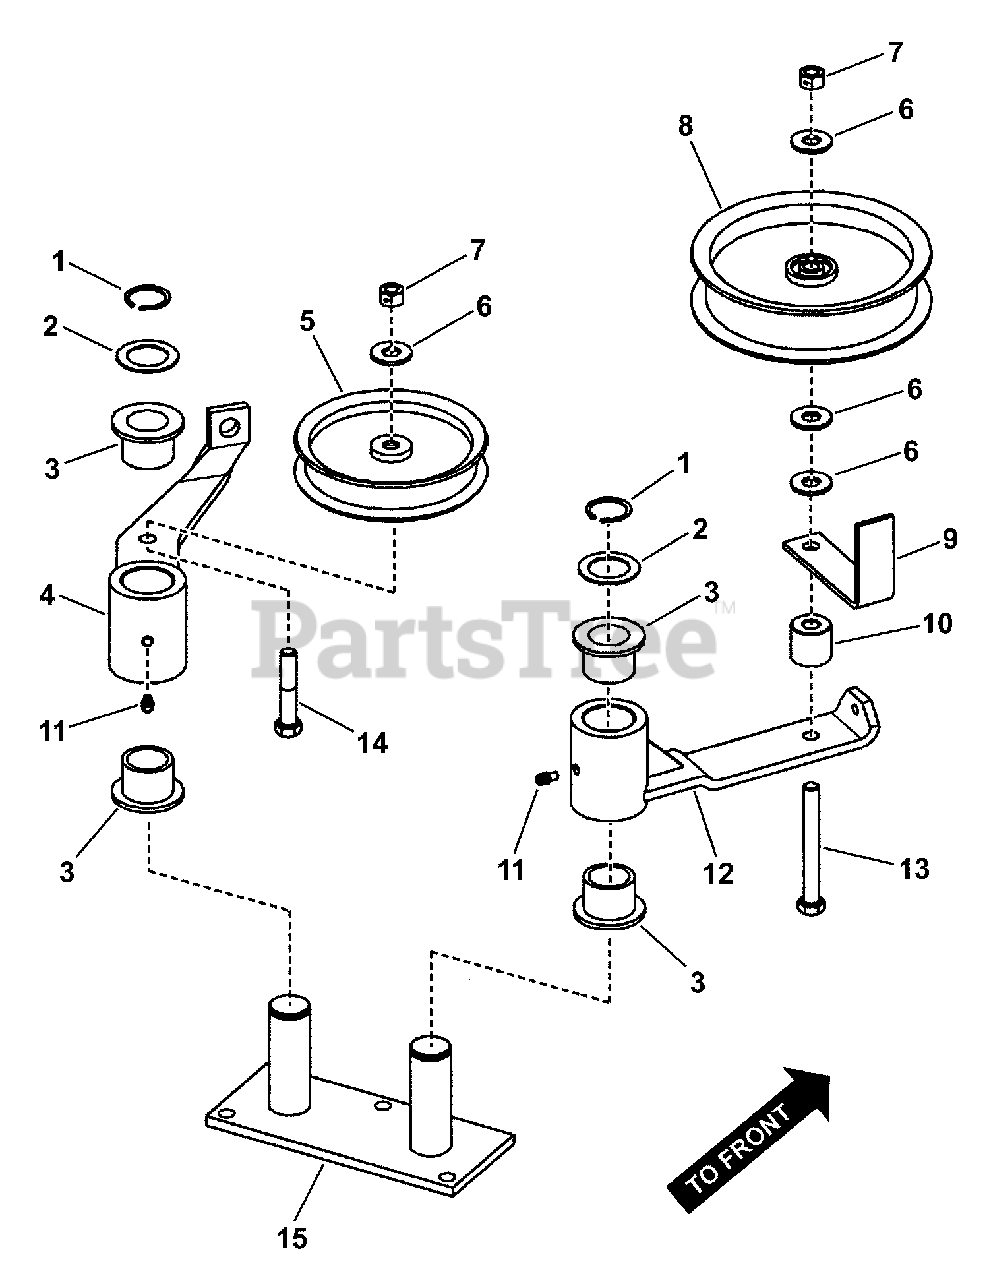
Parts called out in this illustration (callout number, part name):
1	RING, 1" External Retaining
2	BUSHING, 1" I.D. Machine
3	BUSHING, Flange
4	WELDMENT, Idler Arm, Secondary
5	PULLEY, Idler
6	WASHER, 3/8" USS
7	NUT, 3/8-16 Hex Center Lock, GR 5 or B
8	PULLEY, Flat Idler, 5" O.D.
9	RETAINER, Belt - Idler
10	SPACER, Idler Pulley
11	GREASE FITTING, 3/16 Straight (press-in)
12	WELDMENT, Idler Arm, Primary
13	BOLT, 3/8-16 x 3-1/4" Hex Head Cap, GR 5
14	BOLT, 3/8-16 X 2, GD5, CZ
15	WELDMENT, Idler Pivot
